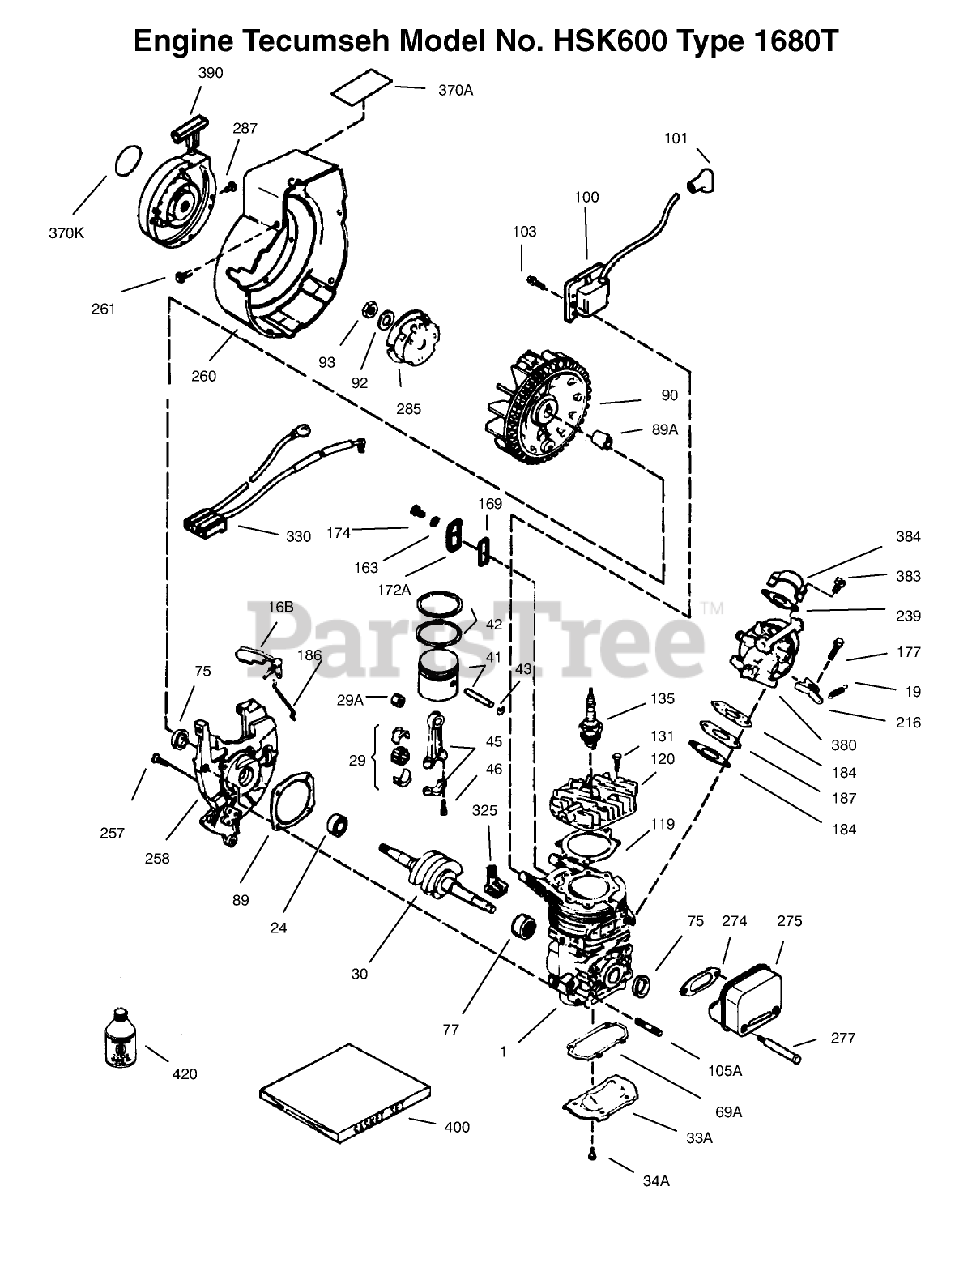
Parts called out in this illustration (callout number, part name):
1	Block Ass-y-Cylinder (Order short block if replacement is required)
16B	Vane-Air
19	Spring-Extention
24	Bearing-Ball
29	Needle Bearing and Liner Set (37 Needles)
29A	Bearing-Cartridge
30	Crankshaft
33A	Plate-Cover
34A	Screw (T-25, 10-24 x 1/2)
41	Piston (Incl. Ref. #43)
42	Ring Set
43	Ring-Retaning
45	Rod Assy.-Connecting (Incl. Ref. #3, 3A 3B)
46	Bolt-Rod, Connecting
69	Gasket-Cover, Cylinder
69A	Gasket-Plate, Cover
75	Seal-Oil
77	Bearing-Cartridge
89A	Blade (20 inch)
90	CARB BODY S
92	Washer-Belleville
93	Nut-Flywheel
100	Solid State
101	Cover-Spark Plug
103	Screw (T-15, 10-24 x 15/16)
119	Gasket-Head, Cylinder
120	Head-Cylinder
131	Screw (T-30, 1/4-20 x 3/4)
135	Spark Plug-Resistor (R C J 8Y)
163	Washer
169	Cover-Compression, Release
172A	Cover-Release, Compression
174	Screw (T-25, 10-24 x 1/2)
177	Screw (5/32 Allen, 1/4-20 x 1)
184	Gasket-Carburetor
186	Governor-Link
187	Spacer
216	Lever-Adjusting, Rpm
239	2060A77 WIZARD ROTA
257	Screw (T-30, 1/4-20 x 5/8)
258	Base Ass-y-Blower Housing (Incl Ref. #20)
260	Housing-Blower
261	Screw (1/4-20 x 1/2)
274	Gasket-Exhaust
275	Muffler (Incl. Ref. #274 277)
277	Screw (1/4-20 x 2-3/4)
285	Cup-Starter
287	Screw (8-32 x 21/64)
325	Clip-Wire
330	Harness-Wire
370A	Decal-Lubrication
370K	Decal-Tecumseh Logo for Top of Recoil Starter
380	Carburetor (Incl. ref. #184)
383	Baffle-Carburetor
384	Screw (T-25, 10-32 x 5/8)
390	Rewind Starter ASM
400	Gasket Set
422	2-Cycle Oil (8oz)
